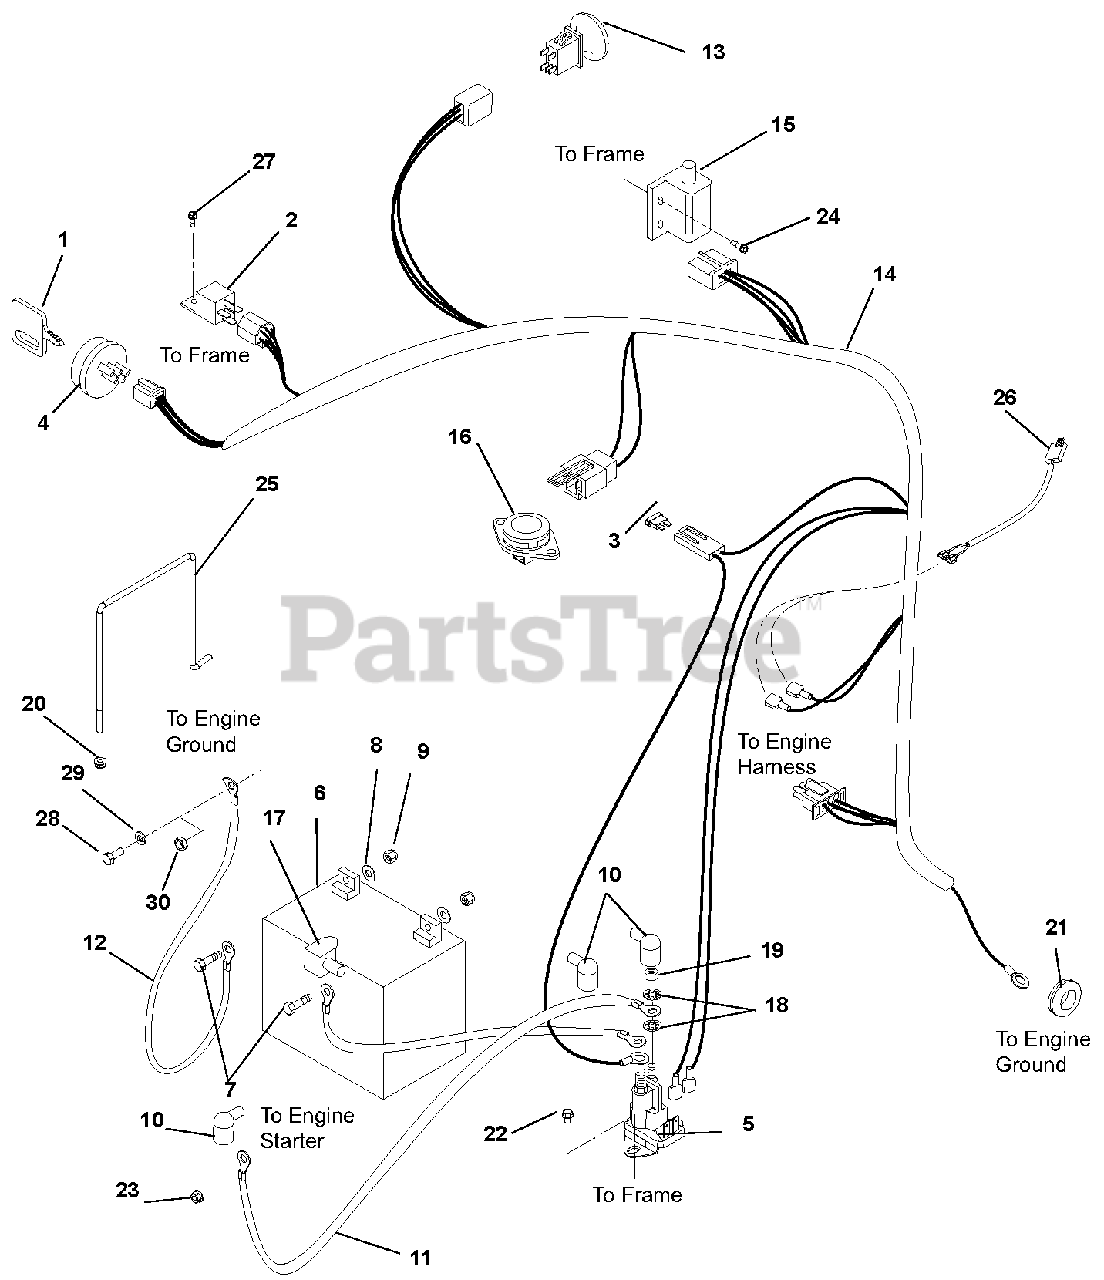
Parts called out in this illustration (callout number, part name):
2	Relay
3	Fuse, 30 AMP
4	KEYSWITCH-IGNITION 3 POS
5	Solenoid
6	Battery, Sealed Maintenance free U1-250 (Purchase replacement locally)
7	Bolt, Hex .25-20 x .75
8	Washer, Flat Steel .281 x .62 x .065
9	Nut, KEPS .250-20
10	Boot, Eyelet Terminal
11	Cable, POS
12	Ground Cable
13	Switch, Clutch With Retainer
14	Harness, Wiring ZT
15	Switch, Double Pole N.O. / N.O.
16	Switch, Snap Mounting (N.O.)
17	Insulator
18	Washer, Locking .31
19	Nut, Jam .31-24
20	Nut, .25-20 Nyloc Flange
21	Grommet .125 x 1.000 ID
22	Screw, Tapping .250-20 x .37 Hex Washer Head
23	Nut, Locking, Top, Flange .25-20
24	Screw, 12-14 x .75 HX
25	Hold Down, Battery
26	Harness, Clutch
27	Screw, Tapping 12-24 x .50 Hex Washer Head
28	Bolt, Hex M8-1.25 x 20
29	Washer, Locking .31 x .078 Regular
30	Nut, Locking, Center, Jam .375-16
